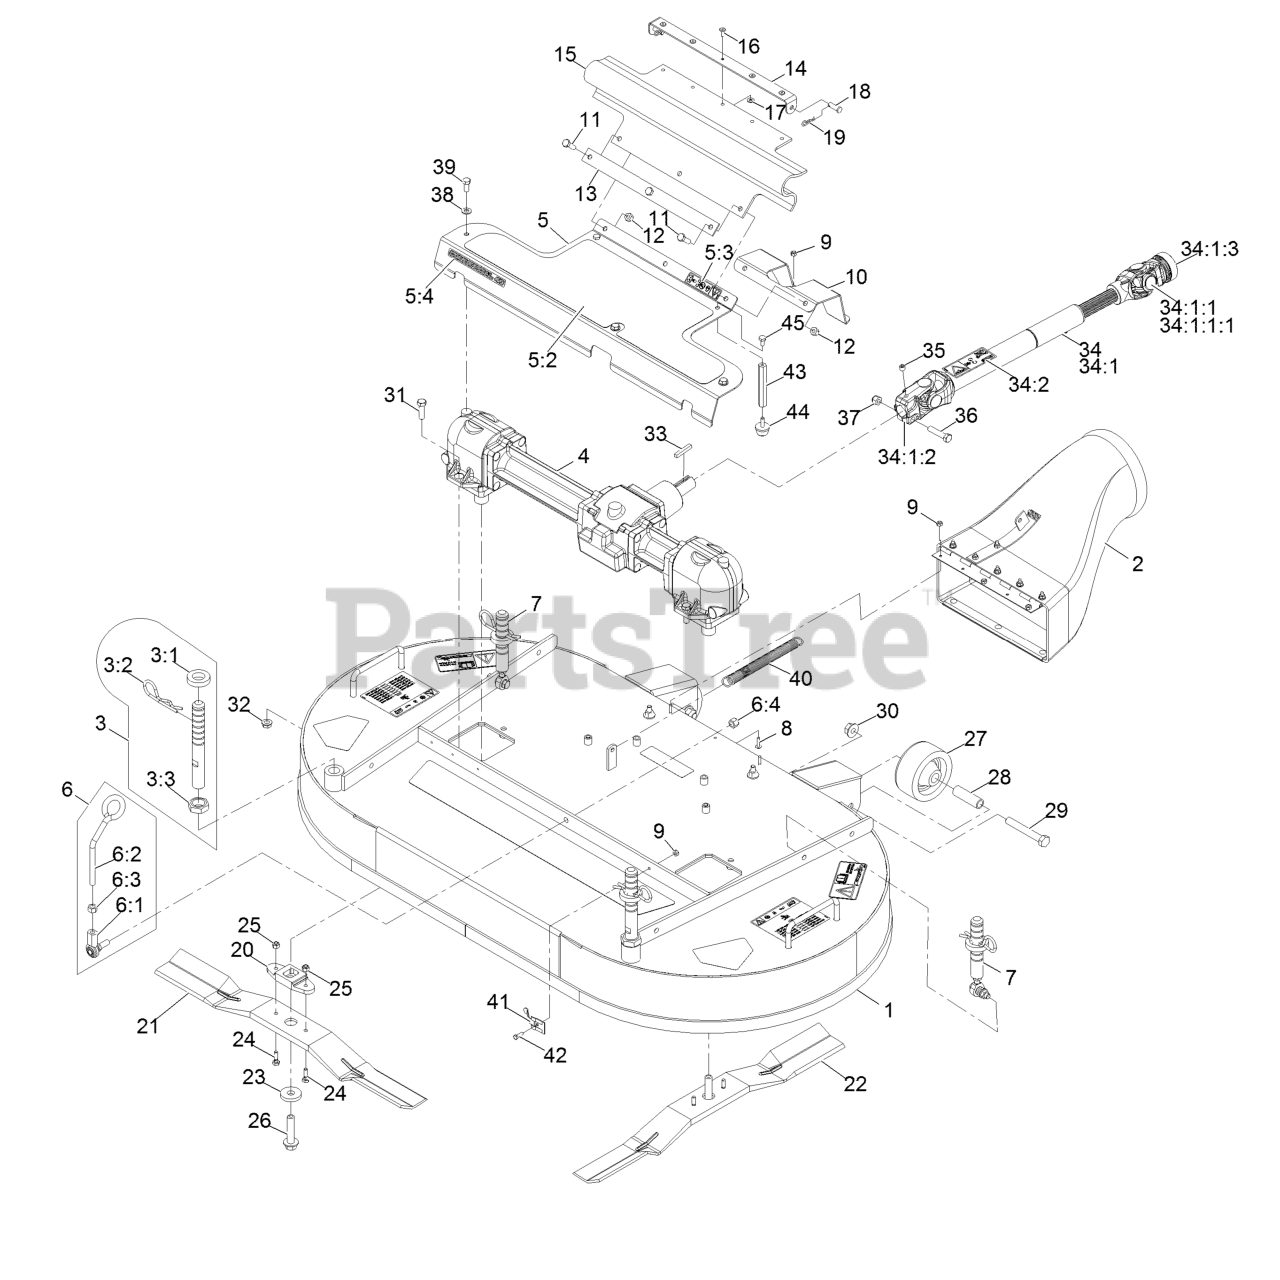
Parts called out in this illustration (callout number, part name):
1	Deck Decal And Baffle ASM
2	Discharge Tube ASM
3	Front Deck Height Adjust ASM
3:1	Spacer-Deck Support
3:2	Pin-Cut Height
3:3	Nut-Jam 7/8-9
4	Gear Box ASM
5	Asm, Gearbox Cover W/Decal (48")
5:2	Pad-Anti Skid
5:3	Decal-Danger
5:4	Decal-Commercial 48
6	Deck Latch ASM
6:1	Balljoint
6:2	Latch-Deck
6:3	Nut-Hex 3/8-24
6:4	Nut-Nyloc 3/8-24
7	Rear Deck Height Adjust ASM
8	Screw-Truss Head #10-24 X 3/4
9	Nut-Nyloc #10-24
10	Guard-Drive Shaft
11	Screw-HH 5/16-18 X 1
12	Nut-Nyloc 5/16-18
13	Strap-Drive, Line Cover
14	Bracket-Guard, PTO
15	Guard-PTO
17	Washer-#10 Std
18	Pin-Clevis 5/16 X 1 49/64
19	Hairpin-Cotter
20	Driver-Blade
21	Blade, RH (48") Red
22	Blade, LH (48") Black
24	Bolt-Shear 1/4-20 X 7/8
25	Nut-Nyloc 1/4-20
26	Bolt-Blade 1/2-20 X 2 1/4
27	Roller-Deck
28	Spacer-Roller
29	Screw-HH 1/2-13 X 3 1/2
30	Nut-Whizlock 1/2-13
31	Screw-HH 3/8-16 X 1 1/4
32	Nut-Whizlock 3/8-16
33	Key-Machine 1/4 X 1/4 X 1 1/2
34	Drive Shaft ASM
34:1	Drive Shaft-Telescoping
34:1:1	U-Joint Kit
34:1:1:1	Fitting-Grease
34:1:2	Yoke-Keyed
34:1:3	Yoke-Quick Disconnect
34:2	Decal-Danger, Driveline
35	Setscrew-3/8-16 X 3/8
36	Screw-HH 3/8-16 X 1 3/4
37	Nut-Nyloc 3/8-16
38	Washer-5/16 SAE
39	Screw-HH 5/16-18 X 3/4
40	Spring-Extension
41	Clip-Deck, Hold Up Rod
42	Screw-HH Machine 10-24 X 5/8
43	Stand-Off
45	Screw-HH 1/4-20 X 1/2
